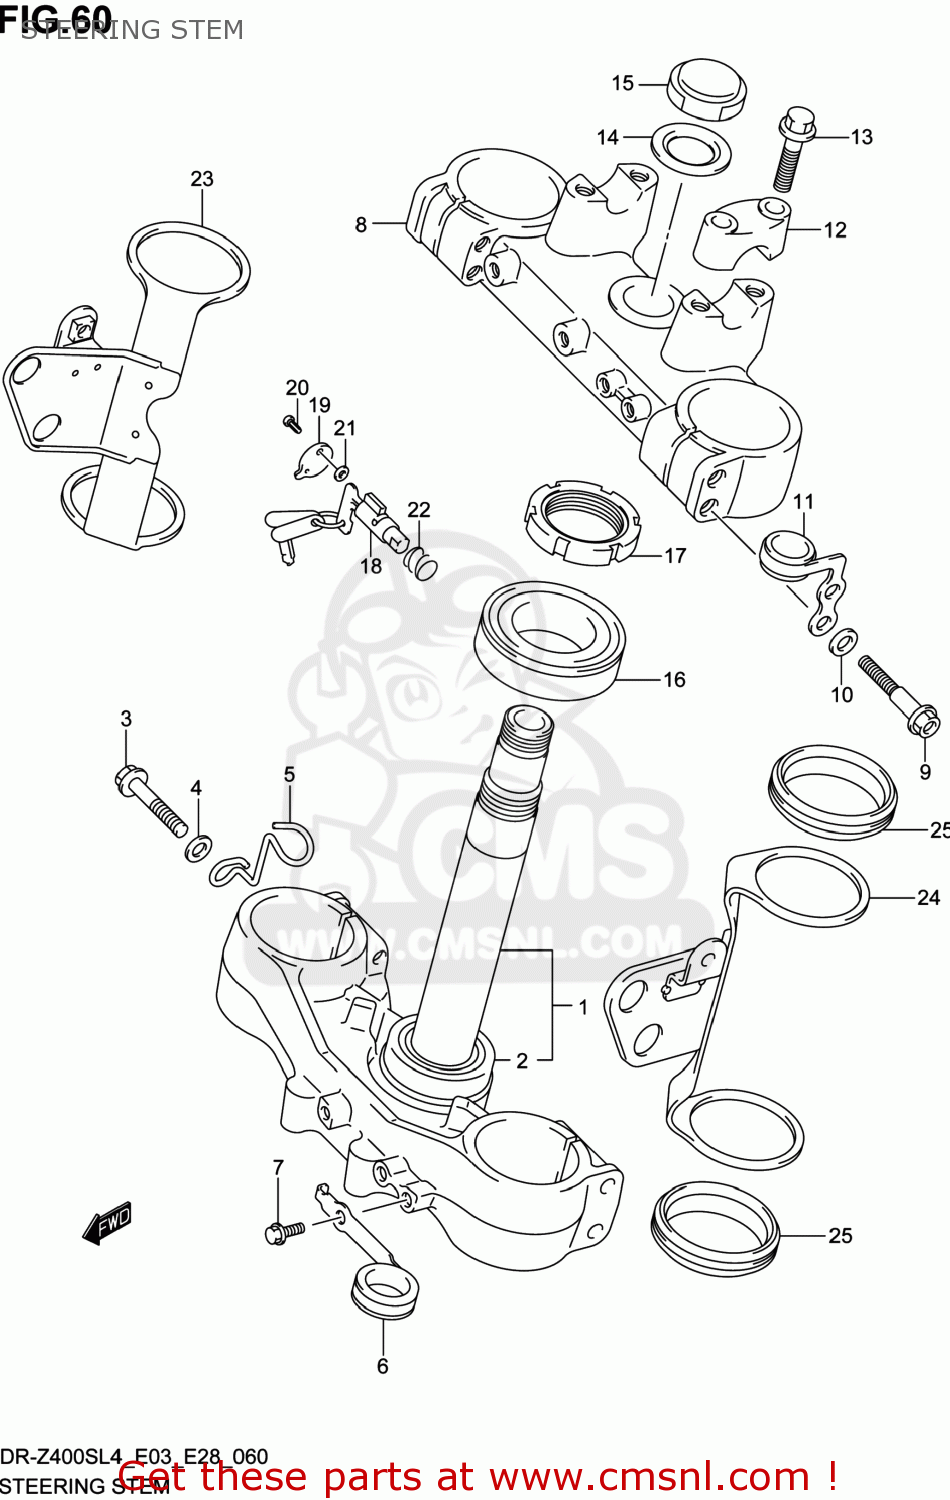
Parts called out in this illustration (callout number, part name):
1	BRACKET,FR FORK UNDER
2	BEARING(30X52X16)
3	BOLT
4	WASHER
5	GUIDE,SPEEDOMETER CABLE
6	GUIDE,CABLE
7	BOLT,PROTECTOR(6X10)
8	BRACKET,FR FORK UPR
9	BOLT
10	WASHER
11	GUIDE,CABLE
12	HOLDER,HANDLEBAR UPR
13	BOLT,HANDLE HOLDER(8X35)
14	WASHER,STEM HEAD
15	NUT
16	BEARING(30X52X16)
17	NUT,STEERING
18	LOCK ASSY,STEERING
19	CAP,STEERING LOCK
20	PIN,STEERING LOCK
21	WASHER,STEERING LOCK
22	SPRING,STEERING LOCK
23	BRACKET,HEADLAMP HOUSING,R
24	BRACKET,HEADLAMP HOUSING,L
25	DAMPER,HEADLAMP HSG BRACKET
